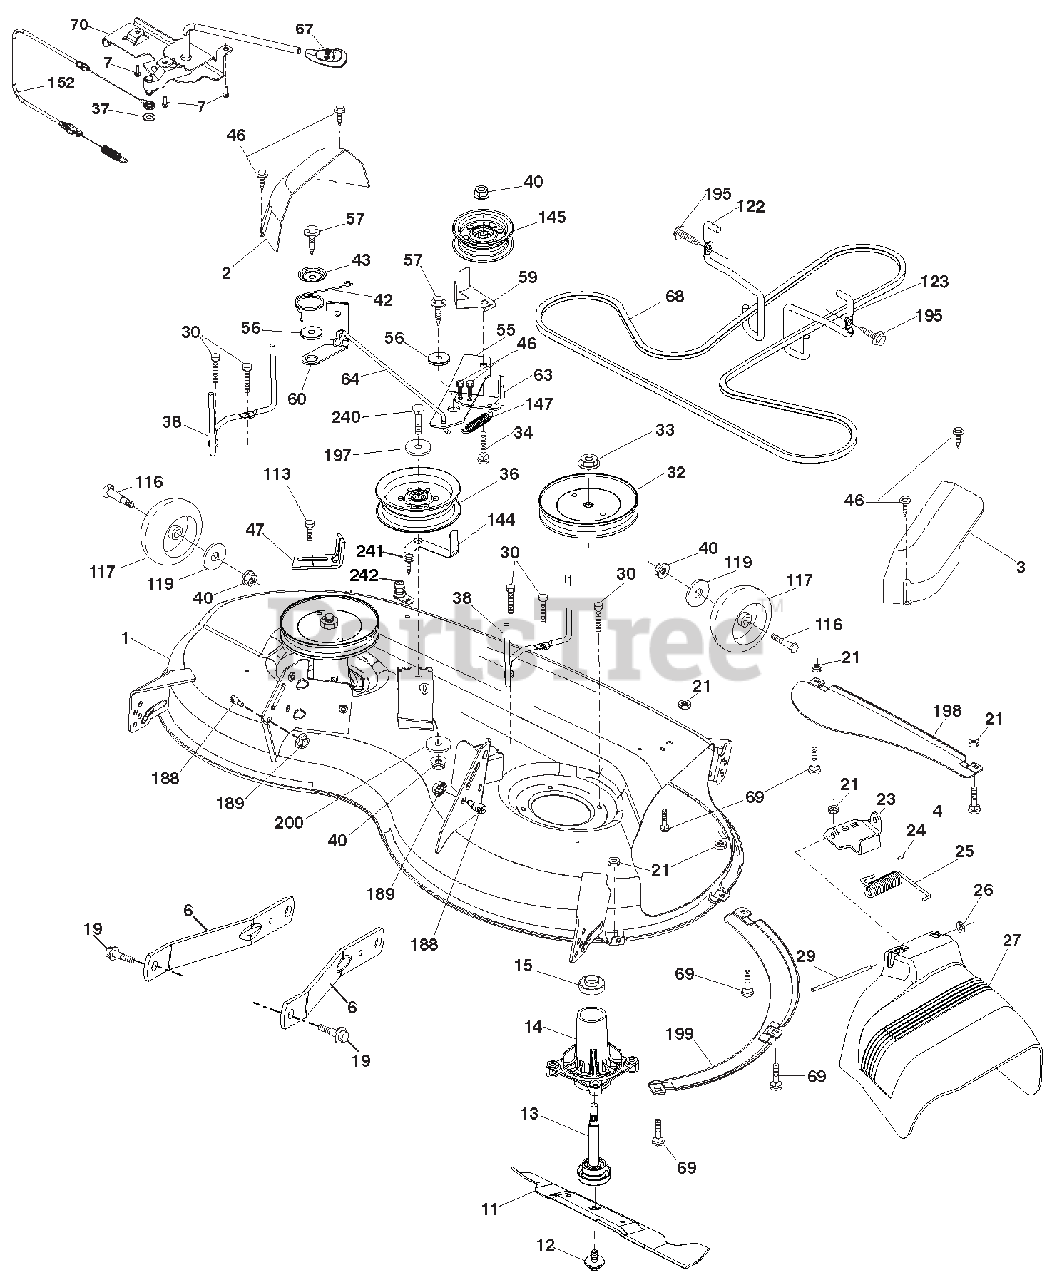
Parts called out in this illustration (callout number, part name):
1	MOWER.HOUSING
2	COVER.MANDREL.LH.46"
3	COVER.MANDREL.RH.46"
4	BOLT.HEX.HD.1/4-20UNC X 3/4
6	ARM.SUSPENSION.MOWER.REAR.LD
11	BLADE.MOWER.46"HI LIFT BAGGER
12	SCREW 7/16-20 X 1
13	SHAFT ASM
14	HOUSING.MANDREL.4PT.SERVICE
15	BEARING
19	BOLT.SHOULDER
21	Nut, Hex, Crownlock 5/16-18
23	BRACKET.DEFLECTOR.38/42"2005
24	CAP.SLEEVE..80X.112.BLK.MOWER
25	SPRING.TORSION.DFL.38/42/46.GR
26	NUT.PUSH.PHOS.& OIL
27	SHIELD.DEFLECTOR.MOWER 46"BLK
29	ROD.HINGE.42/46"
30	SCREW.THD ROLL.DOD PT.HEX
32	PULLEY.MANDREL.5.438 PD.42"
32	MANDREL ASM
33	NUT.FLANGE.LOCK.TOP
34	BOLT.CARR.SH.3/8-16X1-1/2.GR5
36	PULLEY.IDLER.4.50.RAW
37	WASHER.13/32 X 13/16 X 16 GA.
38	KEEPER.BELT.MANDREL.PULLEY
40	Nut, Hex, Flangelock 3/8-16
42	SPRING.TORSION.BRAKE
43	SPRING.TORSION.RETAINER
46	SCREW.THD.ROLL.1/4-20 X 5/8
47	BRACKET.CLUTCH.CABLE
55	IDLER.ARM
56	SPACER.RETAINER
57	SCREW.3/8-16X1.SMGML.TAP/R.BLK
59	GUARD.TUV.IDLER
60	ARM.BRAKE.MOWER.38/46"LH.TEX
63	ARM.BRAKE.MOWER
64	LINAGE.ASM.BRAKE
67	HANDLE.CLUTCH.CABLE.LT TEX.428
68	V-BELT.DRIVE.MWR.MECHANICL.46"
69	BOLT.RDHD.SQNK.5/16-18 X 5/8
70	CLUTCH.ASM.MANUAL
113	BOLT.5/16-18HEX.WHS.HD.LCKSERR
116	BOLD SHLD "A" 2.41 "B" 1.66
117	WHEEL.GAGE.HALF.SPOKED
119	Washer 3/8 x 7/8 x 14 Ga.
122	KEEPER.BELT.ENGINE.LH.LT.TEX
123	KEEPER.BELT.ENGINE.RH.LT.TEX
144	KEEPER.BELT.MOWER
145	PULLEY.IDLER 48"PRIMARY
147	SPRING.RETURN.DECK.38/46"
152	CABLE.CLUTCH.MANUAL
188	STUD.FASTNER.W/'D'ANTI-ROTATIO
189	Nut, Lock Hex Flange 5/16-18 u
195	SCREW.HEXWSH THDR3/8-16X3/4.BL
197	Washer 13/32 x 13/16 x 12 Ga.
198	BAFFLE.CENTER.FRONT
199	BAFFLE.FRONT.RH
200	WASHER.13/32 X 1 X 1/2.11GAHRD
240	BOLT.FIN.HEX.3/8-16X 2-1/4 GR5
242	PORT WASHOUT
244	REPLACEMENT MOWER, COMPLETE
